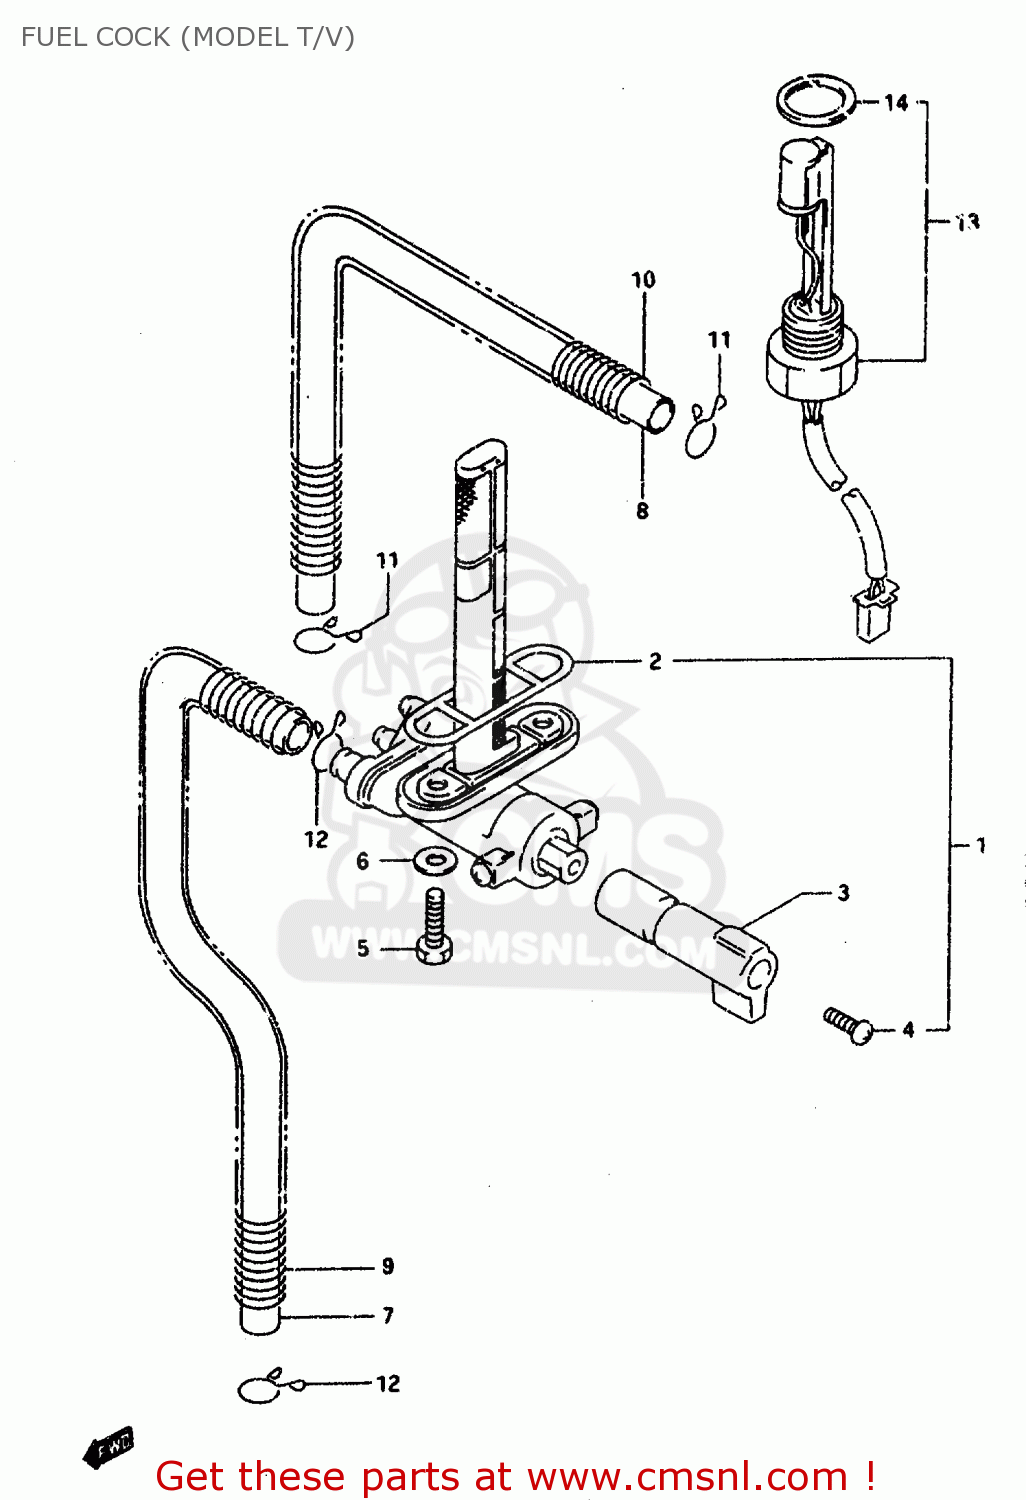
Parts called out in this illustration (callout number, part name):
1	COCK ASSEMBLY,FUEL
2	O RING,FUEL TANK JOINT
3	LEVER COCK FUEL
4	SCREW
5	BOLT(6X20)
6	GASKET(6.4X11.5X0.8) (NAS)
7	HOSE(7X10.2X600)
8	HOSE(7X10.2X600)
9	SPRING
10	SPRING
11	CLIP
12	CLIP
13	GAUGE ASSY,FUEL LEVEL
14	GASKET,FUEL LEVEL GAUGE (NAS)
